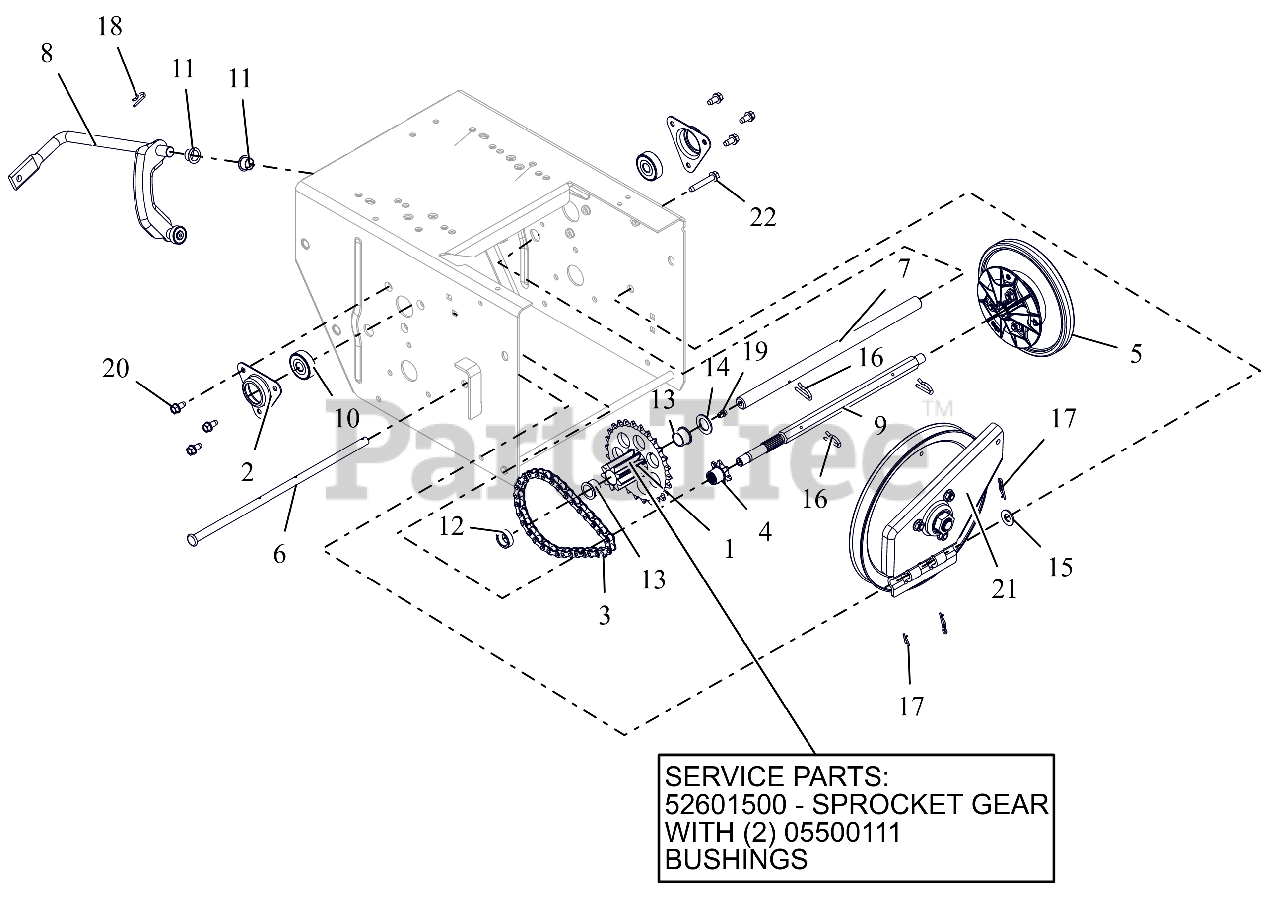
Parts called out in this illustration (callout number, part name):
1	PINION & SPROCKET
1	PINION & SPROCKET W/BUSHINGS
1	BSHG-FLG .625X.750X.500X.875
2	FLANGE, BEARING
3	CHAIN - #41, 32 PITCHES
4	SPROCKET, PINION 7T W/SPLINE
5	DISC, FRICTION DRIVE-ASSEMBLY
6	PIN, PIVOT
7	SHAFT, PINION-HARDENED
8	ARM, SHIFT - ASSEMBLY
9	SHAFT, HEX - HEAT TREATED
10	BRG-BALL .437X1.375X.437
11	BUSHING, POLYLINER-.50 SPLIT
12	BSHG-SLV, .635X.880X.305
13	BSHG-FLG .625X.750X.500X.875
14	WSHR-FL-STL .630X1.005X.062 YZ
15	@WSHR-FL-STL.406X.812X.065 YWZ
16	PIN, SPRING CLIP
17	PIN-HAIR, ENDRIES #25 YWZC
18	CLIP, SPRING
19	ZERK,FITTING .25X.125 DRIVE IN
20	SCR-TAP .25-20X.50 HWH TR YWZ
21	PLATE, SWING ASSEMBLY-DEEP
22	@SCR-TAP .25-20X1.50 HWH TR YZ
